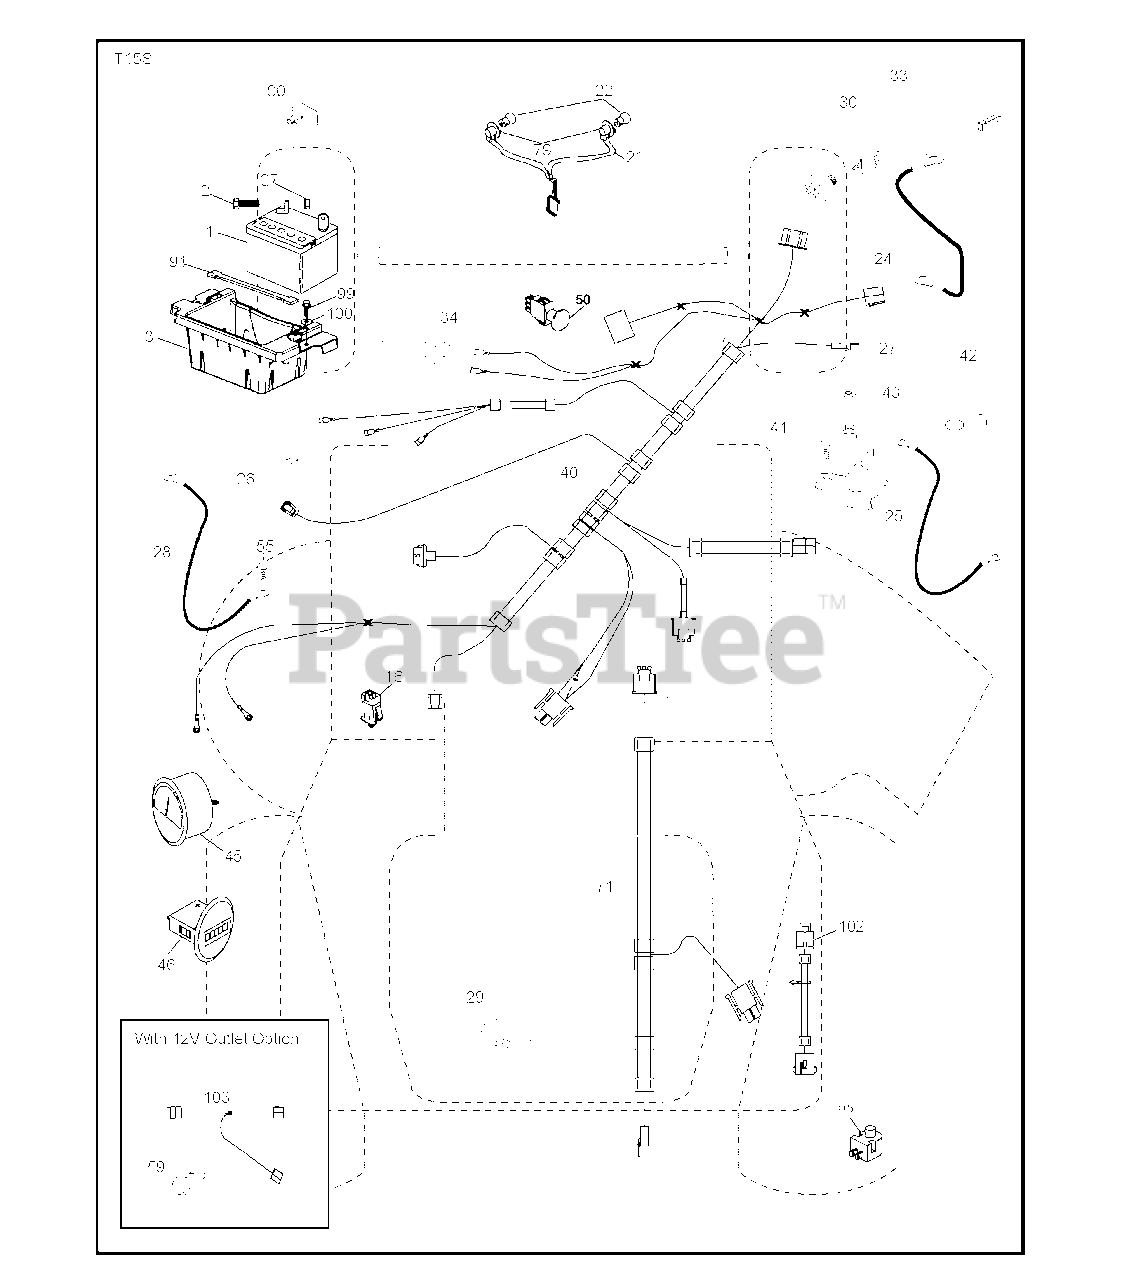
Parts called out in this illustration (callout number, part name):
1	REPL BY 532 12 38-99
8	BOX.BATTERY.MOUNT.FRONT.LT
16	SWITCH INTERLOOK PUSH-IN
21	HARNESS.LIGHT W/4152J BULBS
22	LIGHTBULB
24	CABLE.BATT.POS.WIRE.TG.DA SOL
25	CABLE.STARTER.6G.BL/RED.17.5
26	FUSE 20AMP
27	NUT
28	CABLE GROUND 6 GA 21" 90T BLK
29	SWITCH.SEAT.DELTA.OPC.
30	SWITCH.IGN.DELTA.W.LGH.ROS
33	KEY.CHAIN.BLISTER.PACK.GEN.INT
34	SWITCH LT
40	HARNESS IGN. DASH
41	SCREW
42	TERMINAL COVER
43	SOLENOID.W/BRASS.PLUNG
46	HOURMETER SNAP-IN
50	PTO SWITCH
55	SCREW 5/16"
71	HARNESS-CHASSIS SUB
79	BULB HOLDER ASM.
90	COVER.TERMINAL.BATTERY
91	STRAP, BATTERY MOUNT
99	SCREW HEXWSHR 1/4-20X3/4
102	HARNESS PIGTAIL PCH TEX ROS
105	REVERSE SWITCH
